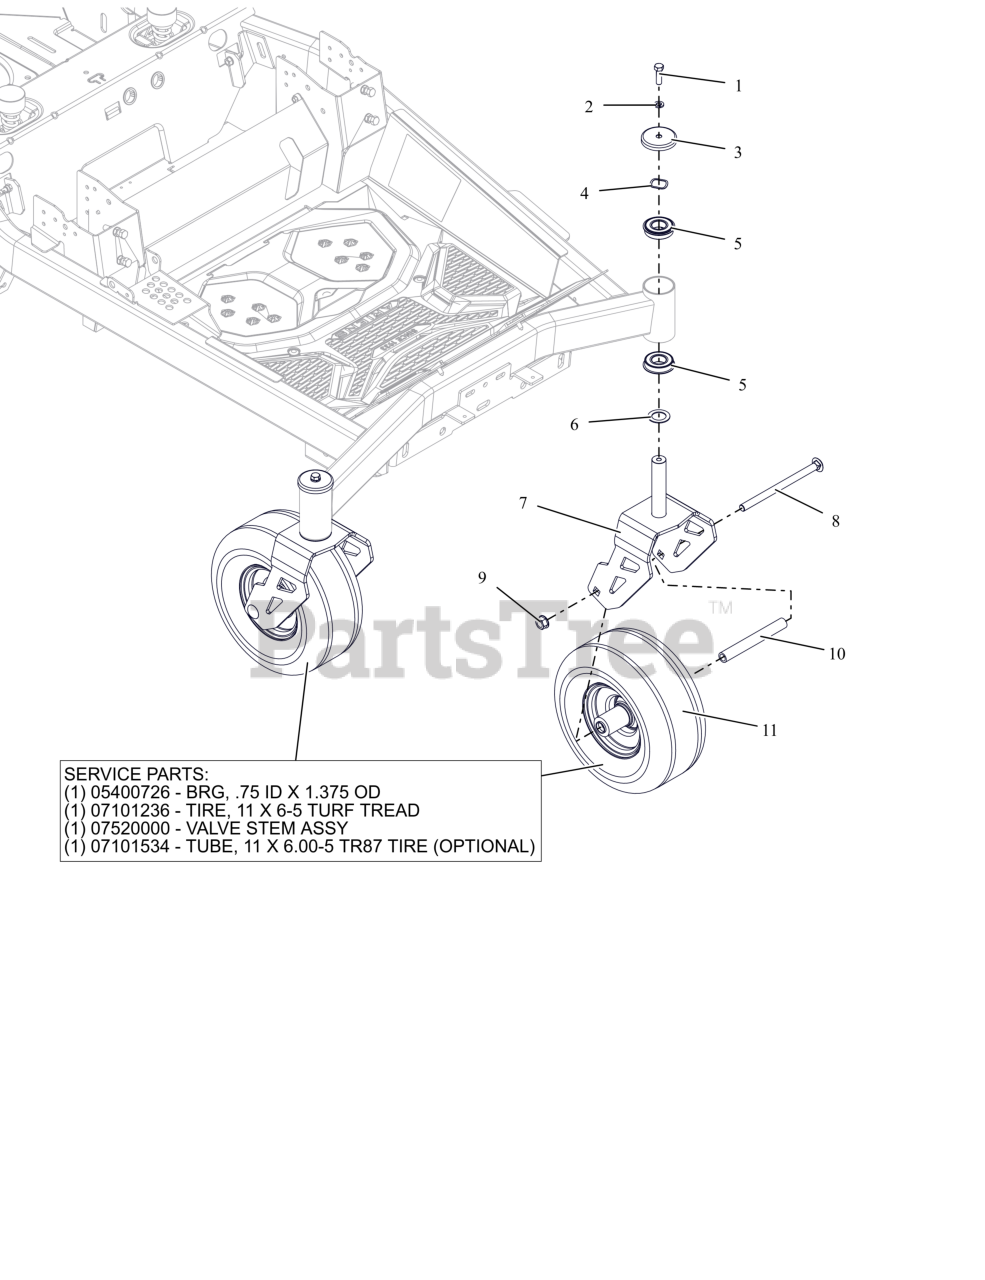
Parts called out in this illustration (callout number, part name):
1	BLT- HEX .38-16X1.25 G5 ZB500
2	WSHR-LK-REG .375X.094 ZB500
3	SHIELD, AXLE BEARING
4	WSHR-WAVE 1.0X1.25X.028 .145FH
5	BEARING, BALL -2.000 OD X 1.000 ID X .5625 W/RING
6	WSHR-HRD-THRS 1.007X1.542X.062
7	WLDMT, CASTER ,FORK,MY23 (BLACK)
8	BLT-RHSN .50-13X7.50 G5 ZCC NS
9	NUT-LK-CTR-FLG .500-13 GG ZCC
10	SPACER, FRONT WHEEL (WIDE 6.0)
11	TIRE/WHEEL ASSY 11X6-5
11	BRG, .75 ID X 1.375 OD
11	LAWN TIRE FRONT, 11/6.00-5 SMOOTH
11	VALVE STEM ASS'Y
11	TUBE- 11X6.00-5 TR87 TIRE
